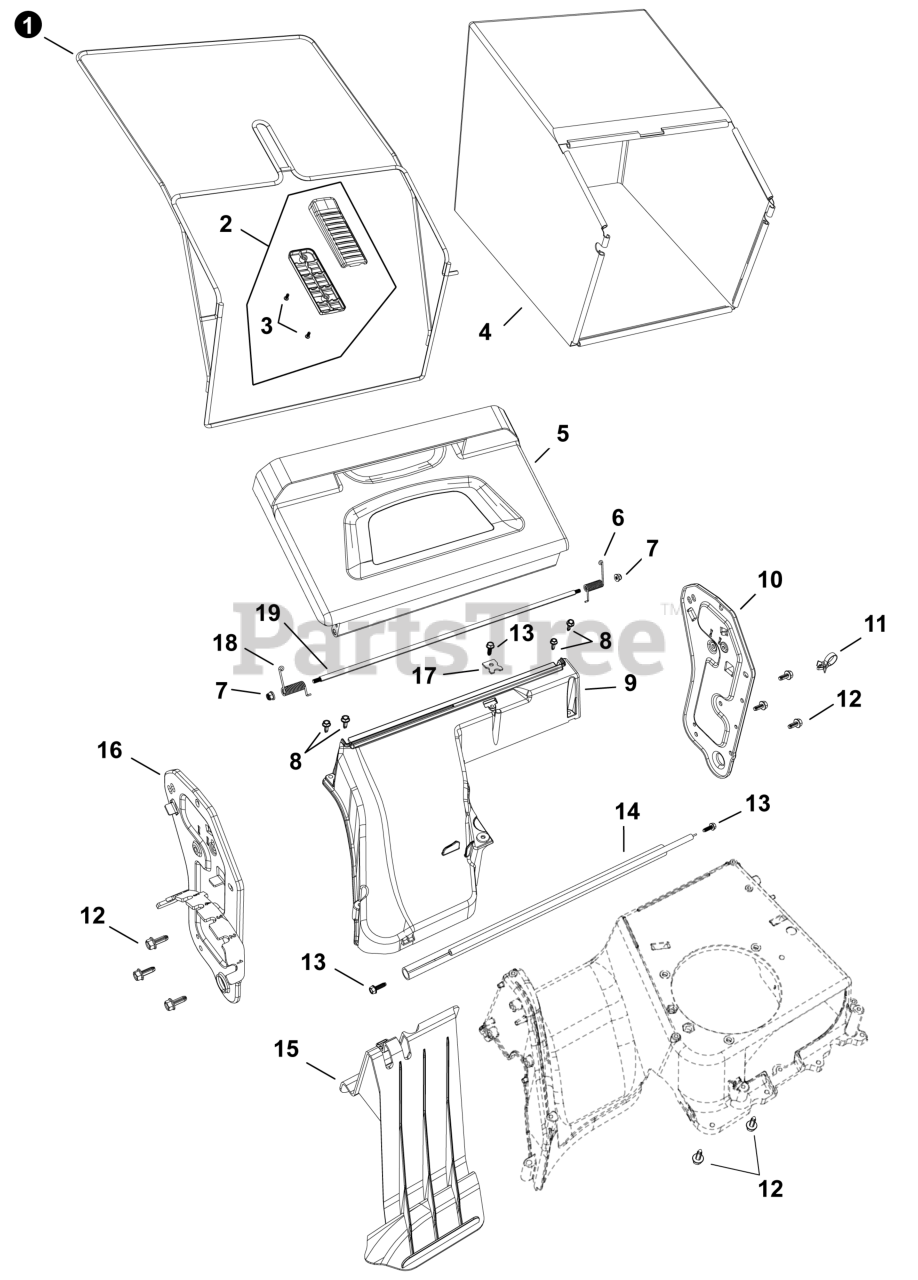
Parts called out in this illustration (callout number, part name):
1	FRAME, GRASS BAG
2	HANDLE KIT, GRASS BAG
3	SCREW
4	BAG, GRASS
5	COVER, REAR DISCHARGE
6	SPRING, DISCHARGE COVER - LEFT
9	COVER, CHUTE
10	BRACKET, LEFT HANDLEBAR
14	SHIELD, DEBRIS
15	PLUG, MULCH
16	BRACKET, RIGHT HANDLEBAR
17	PLATE, BRAKE CABLE
18	SPRING, DISCHARGE COVER - RIGHT
19	ROD, REAR DISCHARGE COVER
